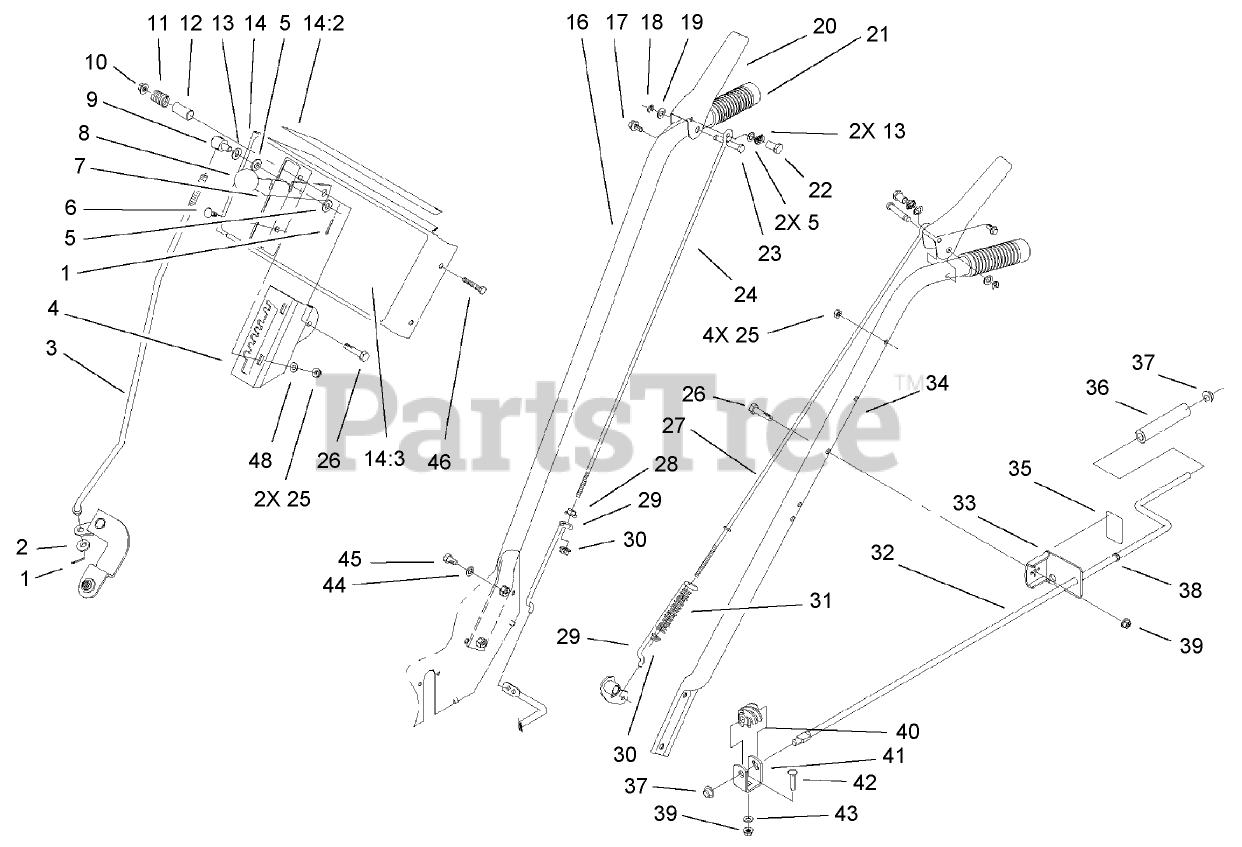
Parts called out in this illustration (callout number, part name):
1	PIN-COTTER
2	WASHER-FLAT
3	ROD - SHIFT
4	MOUNT-SPEED SELECTOR
5	WASHER-FLAT
6	SCREW-CARR
7	SELECTOR-SPEED
9	TRUNNION
10	NUT-HF
11	SPRING
12	SPACER
13	WASHER-SPRING
14	CONTROL PANEL ASM
14:2	DECAL - ESCUTCHEON BACK
14:2	DECAL-ESCUTCHEON BACK (only on: 38053)
14:3	DECAL-CONTROL PANEL
17	SCREW-HHF
18	RING-CLIP
19	WASHER-PLAIN
20	HANDLE-CONTROL
22	POST-MOUNTING, LINKAGE
23	PIN-LEVER, CONTROL
24	ROD-UPPER ENGAGE AUGER
25	NUT-LOCK, NI
26	SCREW-HH
27	ROD - UPPER TRACTION
28	NUT-HF
29	ROD - LOWER TRACTION
30	NUT-HHF
31	SPRING
32	ROD-CONTROL, CHUTE
35	DECAL-CHUTE DIRECTION
36	GRIP-CONTROL, CHUTE
37	NUT-PUSH
39	NUT-LOCK, NI
40	GEAR-WORM, CHUTE
41	BRACKET-WORM
42	SCREW-CARR
43	WASHER-LOCK
44	WASHER-BELLEVILLE
45	SCREW-HWHTF
46	SCREW-HH
48	WASHER-FLAT
